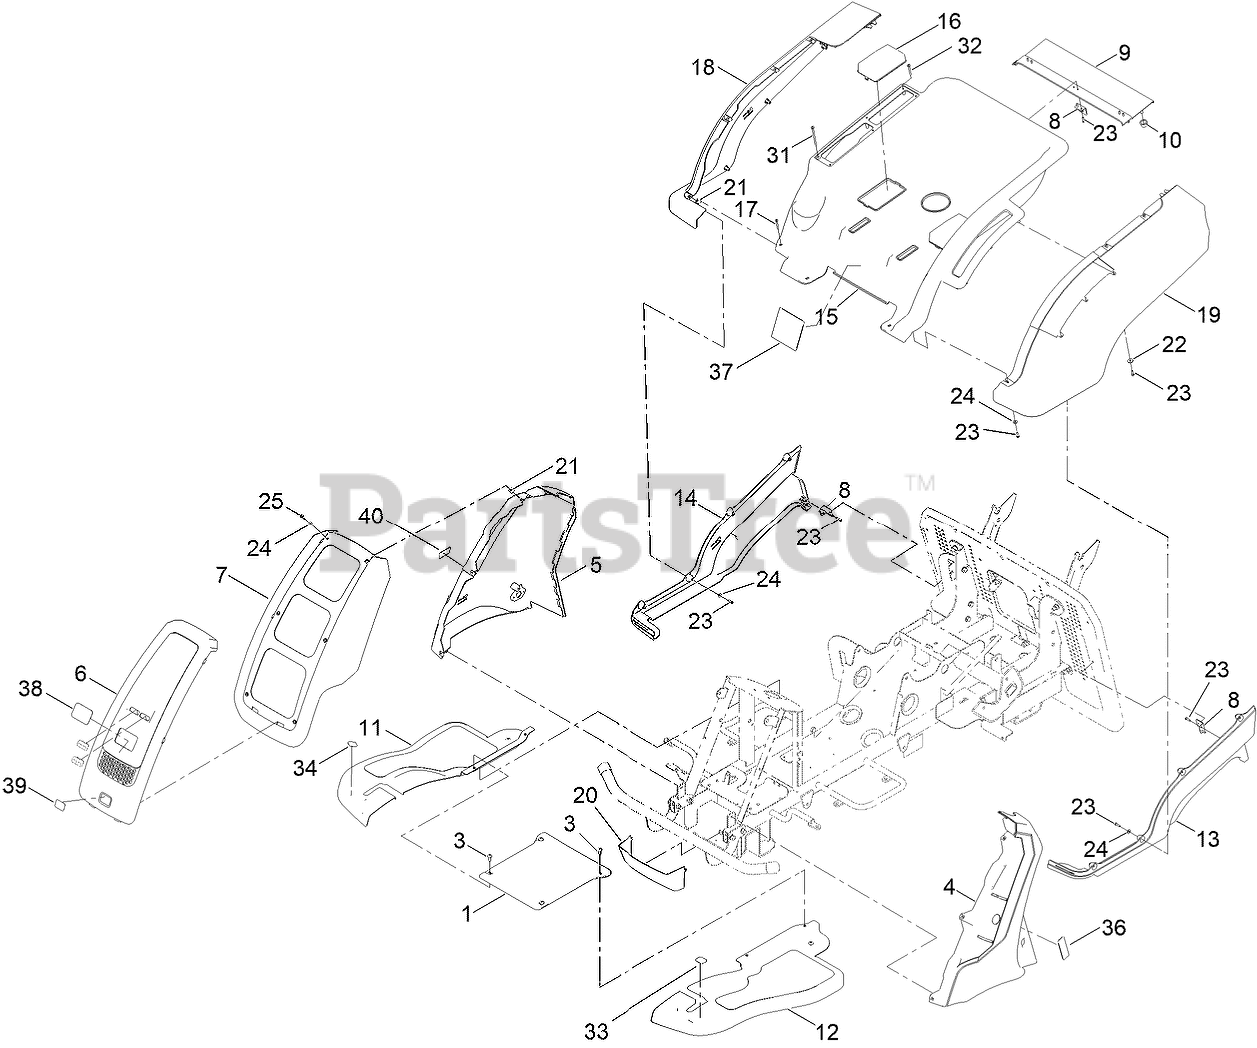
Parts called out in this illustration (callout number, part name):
1	PLATE, CENTRE
4	COVER, LEFT REAR (STEERING)
5	COVER, RIGHT REAR (STEERING)
6	COVER, FRONT (STEERING)
7	COVER, MIDDLE (STEERING)
8	BRACKET, COVER ATTACHMENT
9	BODYWORK, COVER REAR
10	SPACER
11	PANEL, FOOT (RH)
12	PANEL, FOOT (LH)
13	BODYWORK, COVER LOWER LEFT
14	BODYWORK, COVER LOWER RIGHT
15	COVER, MIDDLE
16	COVER, HOC
17	BOLT PH
18	BODYWORK, COVER RIGHT UPPER
19	BODYWORK, COVER LEFT UPPER
20	COVER, FRONT LOWER
21	CLIP, BOLT
22	WASHER
24	WASHER
33	DECAL - BRAKE
34	DECAL - PROPEL
36	DECAL - PARKING BRAKE
37	DECAL - DANGER
38	DECAL - TORO LOGO
39	DECAL - ERIDER BATTERY
40	DECAL - CHARGING PORT
